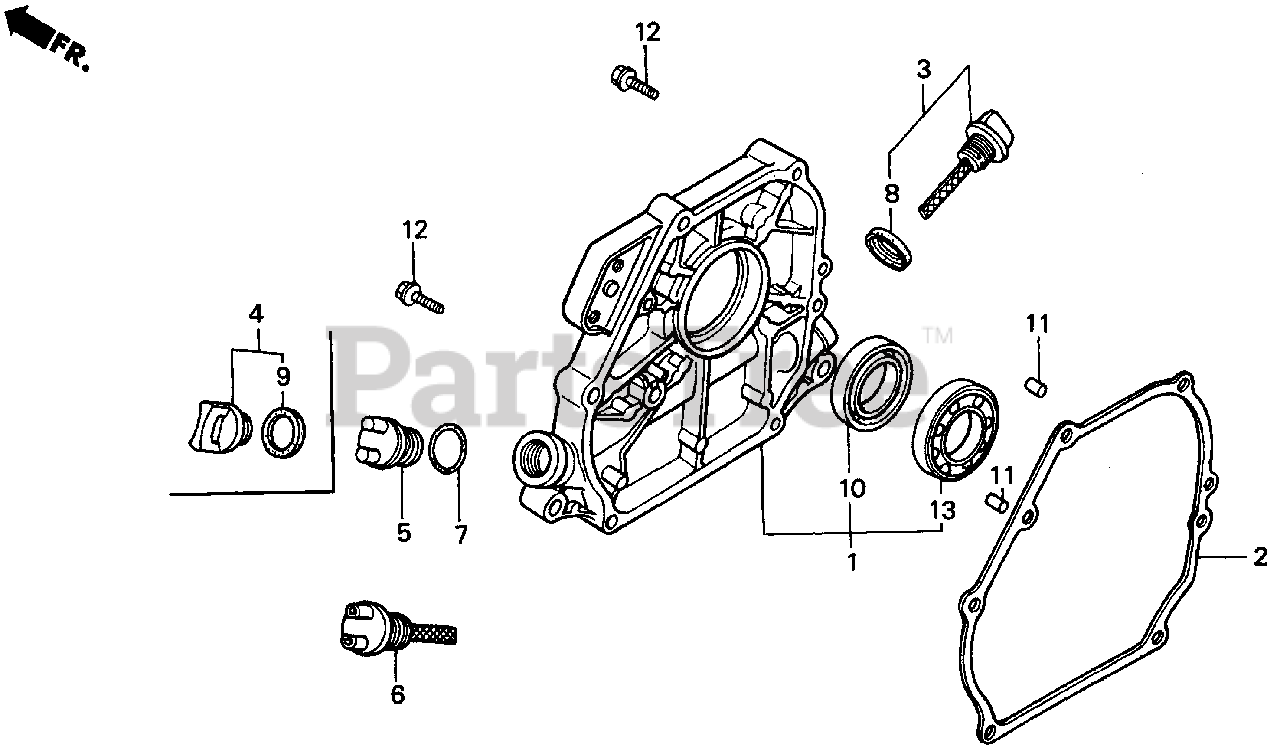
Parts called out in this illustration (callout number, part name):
1	COVER ASSY., CRANKCASE
2	GASKET, CASE COVER (NON-ASBESTOS)
3	CAP ASSY., OIL FILLER
4	CAP ASSY., OIL FILLER
8	GASKET, OIL FILLER CAP
9	GASKET, OIL FILLER CAP
10	OIL SEAL (25X41X6)
11	PIN A, DOWEL (8X14)
12	BOLT, FLANGE (8X32)
13	BEARING, RADIAL BALL (6205)
